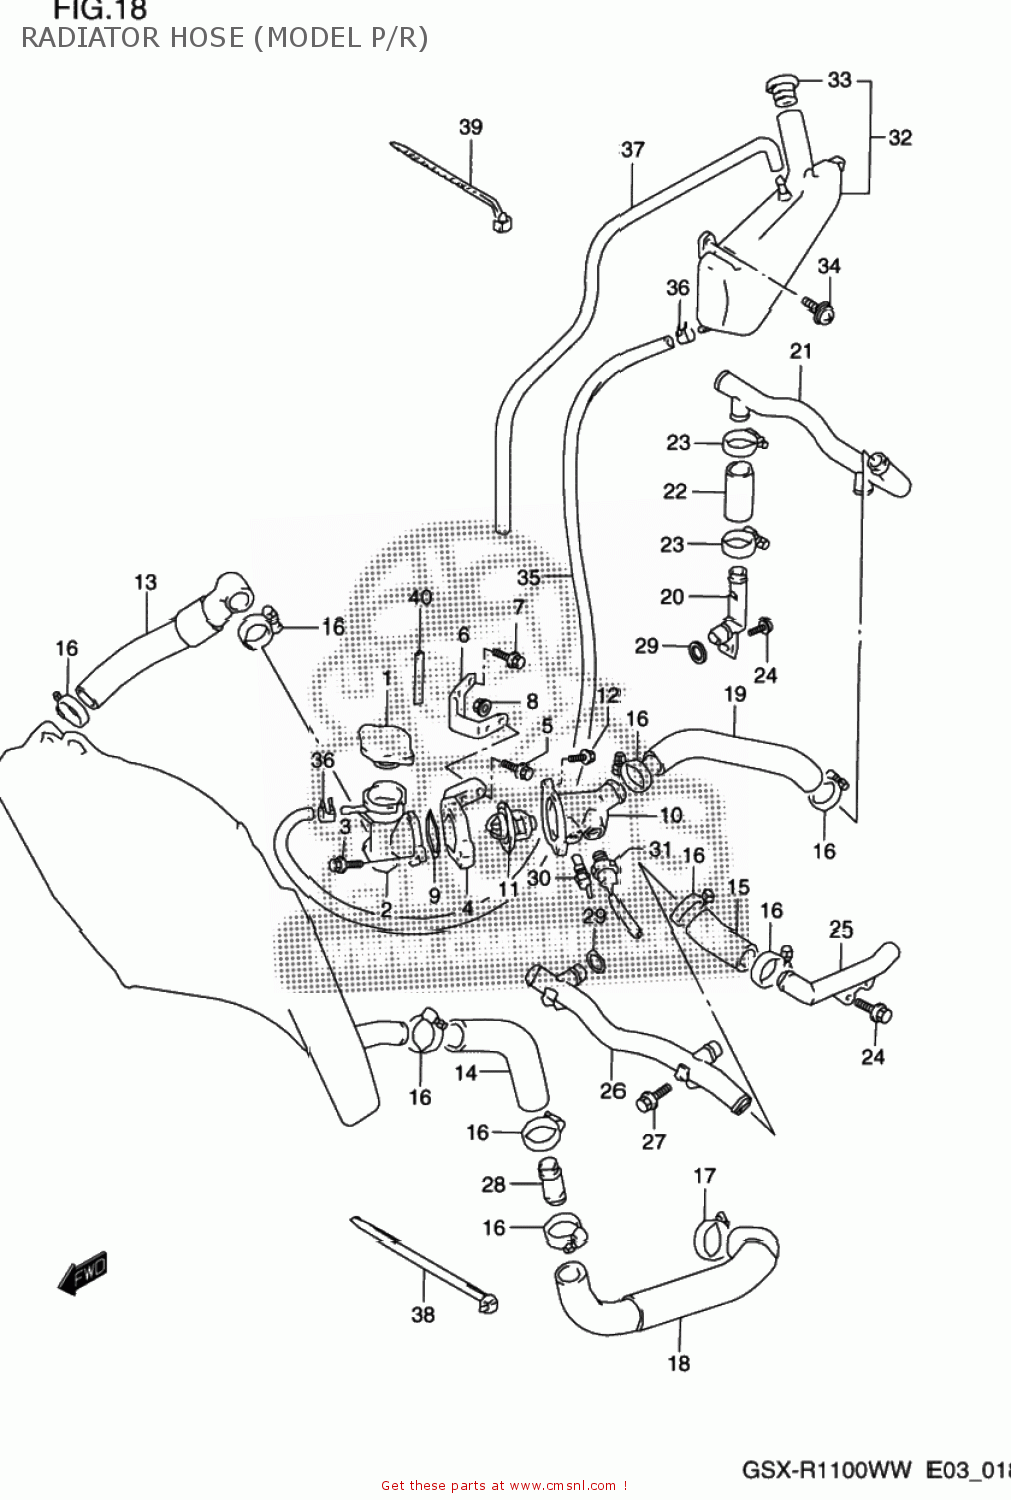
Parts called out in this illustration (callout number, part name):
1	CAP,RADIATOR 1.1
2	CONDUCTION,RADIATOR
3	BOLT 6X16
4	BRACKET,CONDUCTION
5	BOLT 6X20
6	BRACKET,CONDUCTION BRAKE
7	BOLT 6X16
8	NUT
9	O RING(D:2.4,ID:43.2)
10	CONNECTOR,THERMOSTAT,INLET
11	THERMOSTAT,WATER
12	BOLT
13	HOSE,WATER
14	HOSE,RADIATOR OUTLET
15	HOSE,WATER
16	CLAMP
17	CLAMP
18	HOSE,WATER PUMP INLET
19	HOSE,HEAD OUTLET
20	PIPE,HEAD OUTLET
21	PIPE COMP,HEAD OUTLET
22	HOSE,WATER
23	CLAMP
24	BOLT
25	PIPE,CYLINDER SIDE
26	PIPE,CYLINDER INLET
27	BOLT
28	UNION,HOSE JOINT
29	O RING(D:3.2,ID:17.8)
30	GAUGE ASSY,WATER TEMP
31	SWITCH COMP,RADIATOR FAN
32	TANK ASSY,RESERVOIR
33	CAP,RESERVOIR TANK
34	SCREW(6X20)
35	HOSE,RESERVOIR TANK INLET
36	CLIP
37	HOSE,RESERVOIR TANK OVERFLOW
38	CLAMP
39	CLAMP(L:165)
40	MOLDING,FUEL TANK RR
